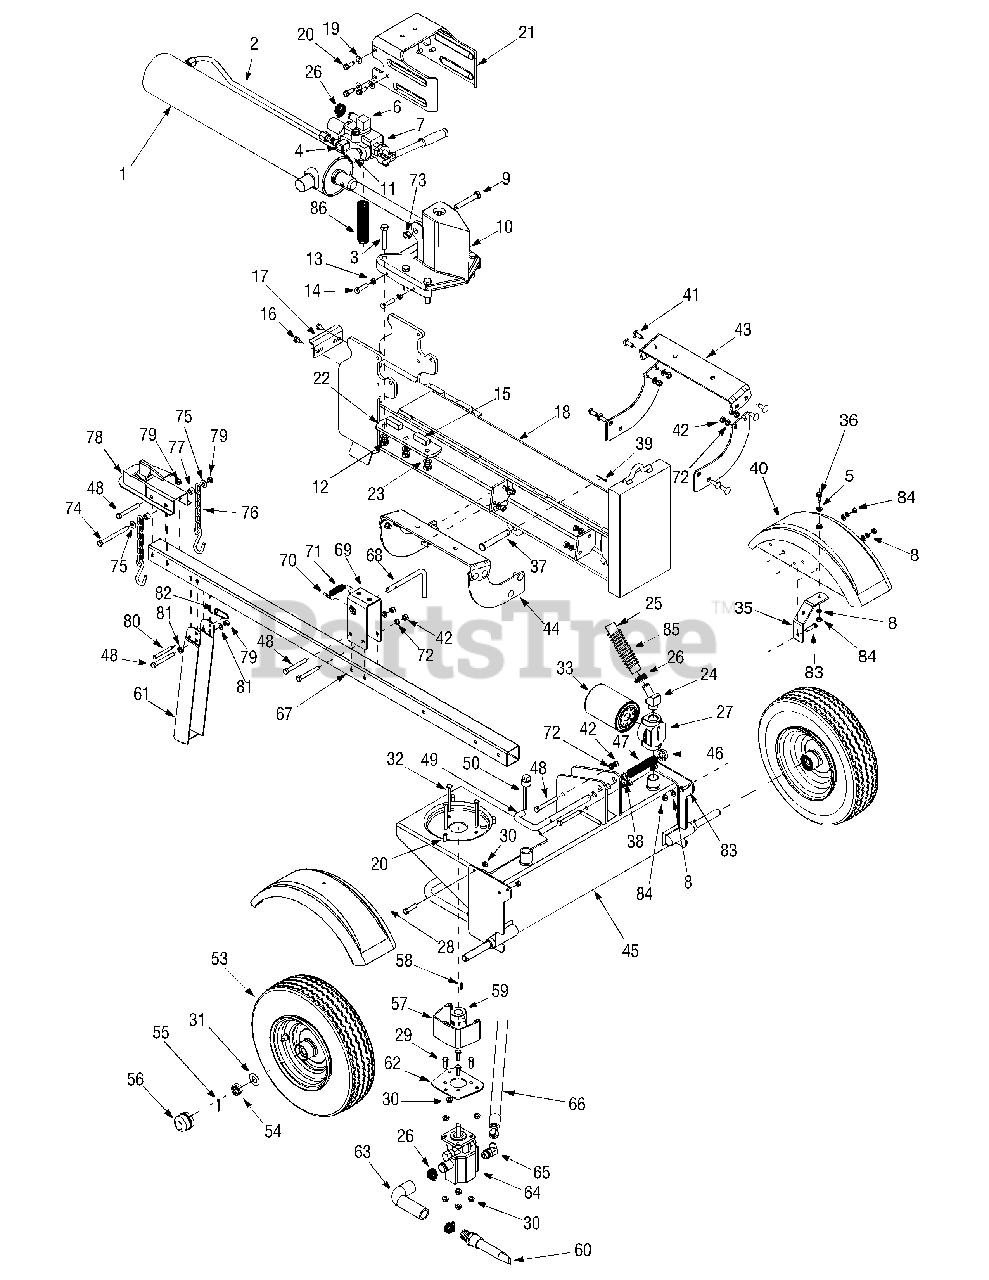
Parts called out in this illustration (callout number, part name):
1	Hydraulic Cylinder
2	Hydraulic Tube
3	Hex Cap Screw 1/2-20 x 2.75
4	90 Degree Solid Adapter
5	Flat Washer, .434 x .880 x .062
6	Return Elbow
8	Lock Washer, 5/16
9	Hex Cap Screw 1/2-13 x 3.25
10	Wedge Assembly
11	Nipple Pipe 1/2-14
12	Lock Nut 1/2-20
13	Hex Jam Nut 3/8-24
14	Hex Cap Screw 3/8-24 x 1.5
15	Adjustable Gib
16	LD Screw 5/16-18 x.75
19	Flat Washer.406 ID x.875 OD
20	Hex Washer Screw 3/8-16 x 1.
23	Lock Washer 1/2
24	Adapter 3/4-14
25	Return Hose 3/4" ID x 44"
26	Hose Clamp 5/8"
27	Filter Housing
28	Hex Screw, 5/16-18 x .75
29	Hex Screw , 5/16-18 x 1.0
30	Hex Flange Nut, Nylon, 5/16-18
31	Flat Washer.760 ID x.500 OD
32	Hex Bolt 5/16-18 x 3.25"
33	Oil Filter
36	Hex Screw, 5/16-18 x .875
38	Flat Washer.635 ID x.93 OD
40	Fender, Black
41	Carriage Bolt 3/8-16 x 1.0
42	Hex Nut 3/8-16
47	Compression Spring
48	Hex Bolt 3/8-16 x 3"
50	Vented Dipstick
51	Hex Screw 5/16-24 x 3.25
53	Wheel Assembly
53	Cone Bearing
53	Grease Retainer
54	Slotted Nut 3/4-16
57	Coupling Shield
58	Square Key 3/16" x.75
59	Flexible Coupling .750 x .500
59	Flexible Coupling .875 x .500
59	Flexible Coupling .875 x .437
61	Jack Stand
63	Hose
64	Gear Pump (11 gpm)
64	Pump Kit
64	Gear Pump (9.5 gpm)
65	45 degree Elbow
66	High Pressure Hydraulic Hose
67	Tongue Tube Assembly
68	Tongue Latch Rod
71	Compression Spring
72	L-Washer 3/8"
73	Hex Lock Nut 1/2-13
74	Hex Cap Screw 3/8-16 x 4.25
75	Flat Washer.385 ID x.870 OD
76	Chain
77	Spacer.375 ID x.625 OD
78	Hitch Coupler
79	Hex Lock Nut 3/8-16
80	Clevis Pin
81	Flat Washer.375 ID x.738 OD
83	Hex Screw, 5/16-18 x .875
84	Hex Nut, 5/16-18
85	Hose Guard
86	Hose Guard
